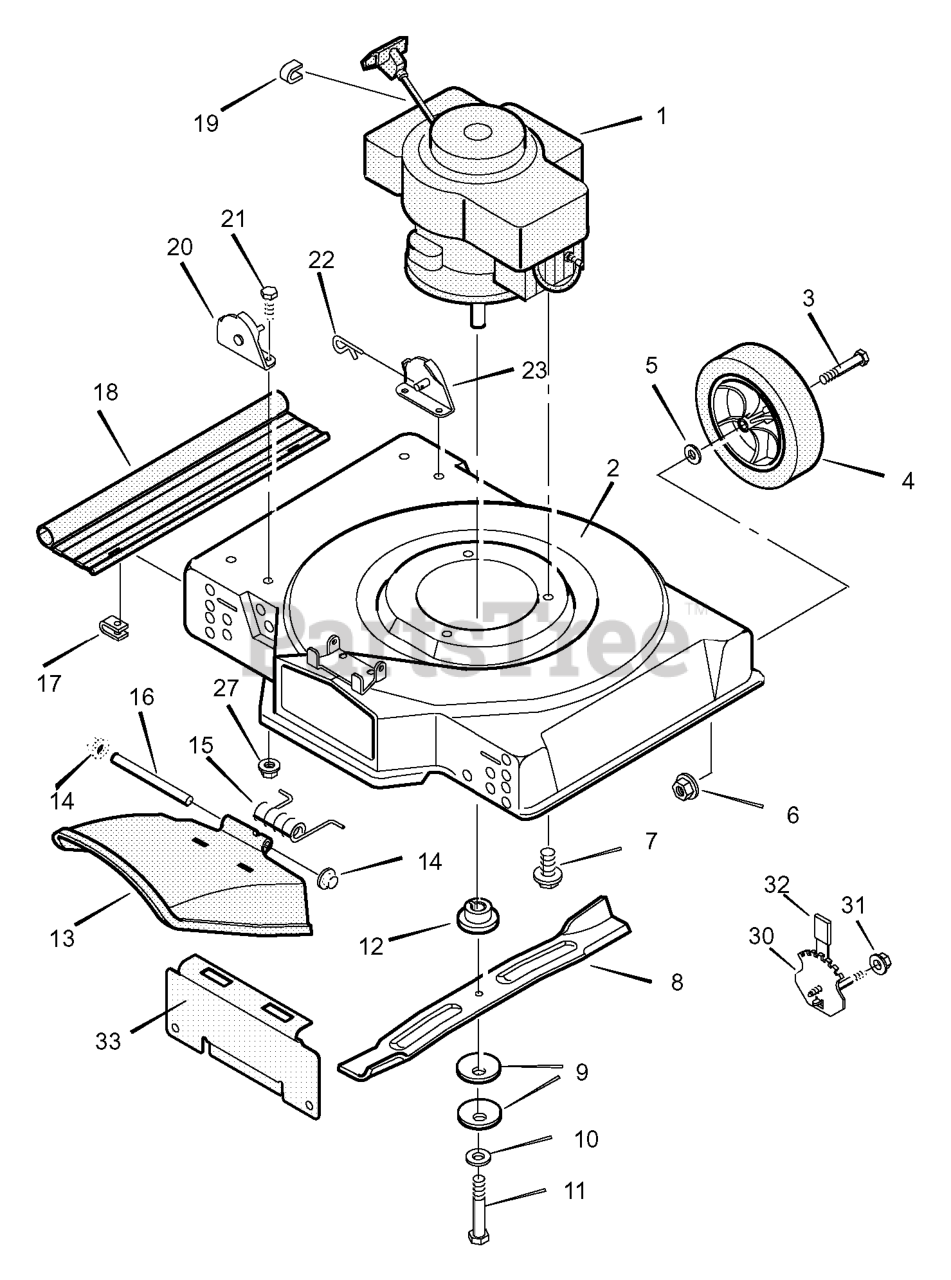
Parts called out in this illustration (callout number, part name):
1	Engine *
2	Housing
3	Bolt, Axle
4	Wheel and Tire
6	Locknut, Flange
7	Bolt, Engine
9	Washer, Belleville
11	Bolt, Hex
12	Adapter, Blade
13	Deflector, Chute
14	Push-On Cap
16	Pin, Pivot
17	Retainer
18	Deflector, Rear
19	Stop, Rope
20	Bracket, Right Handle
22	Pin, Hair
23	Bracket, Left Handle
27	Nut
30	Adjuster, Height
31	Locknut, Flange
33	Plate, Mulcher
